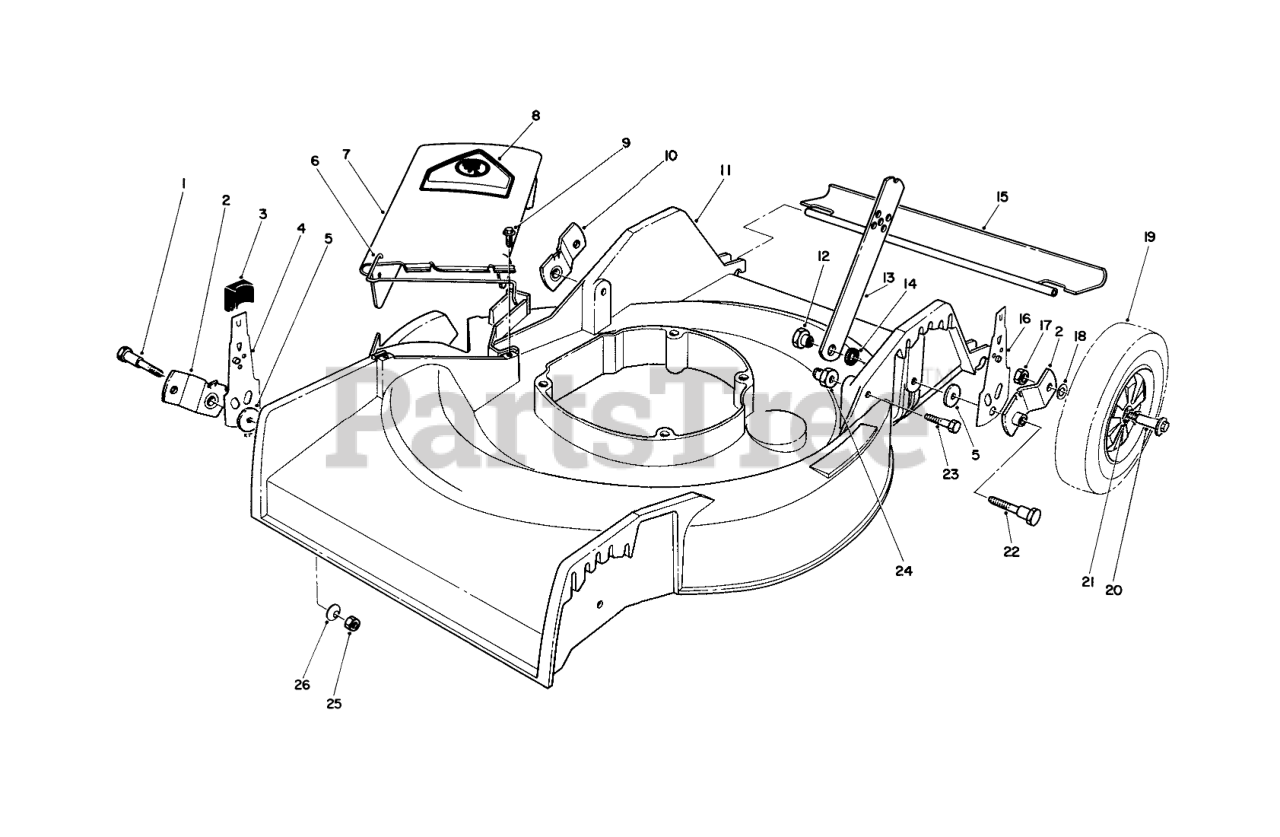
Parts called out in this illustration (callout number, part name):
1	5/16-18 PIVOT SCREW
2	Pivot Arm
3	KNOB-ARM
4	RH FRONT SPRING ARM ASM
5	PIVOT WASHER
6	SPRING HINGE
7	Deflector Assembly (Incl. Ref. #6 & 8)
8	DECAL-DANGER
9	SCREW-HWH
10	Pivot Arm
11	HOUSING W/ DECAL
12	HANDLE PIVOT NUT
13	HANDLE LATCH
14	SPACER
15	SHIELD - TRAILING
16	REAR SPRING ARM ASM
17	Nut
18	WASHER
19	Wheel & Tire Assembly (Incl. Ref. #21)
20	BOLT-WHEEL
21	BUSHING
22	PIVOT SCREW
23	SCREW-HH
24	HANDLE PIVOT NUT
25	NUT-LOCK, NI
26	WASHER-BELLEVILLE
